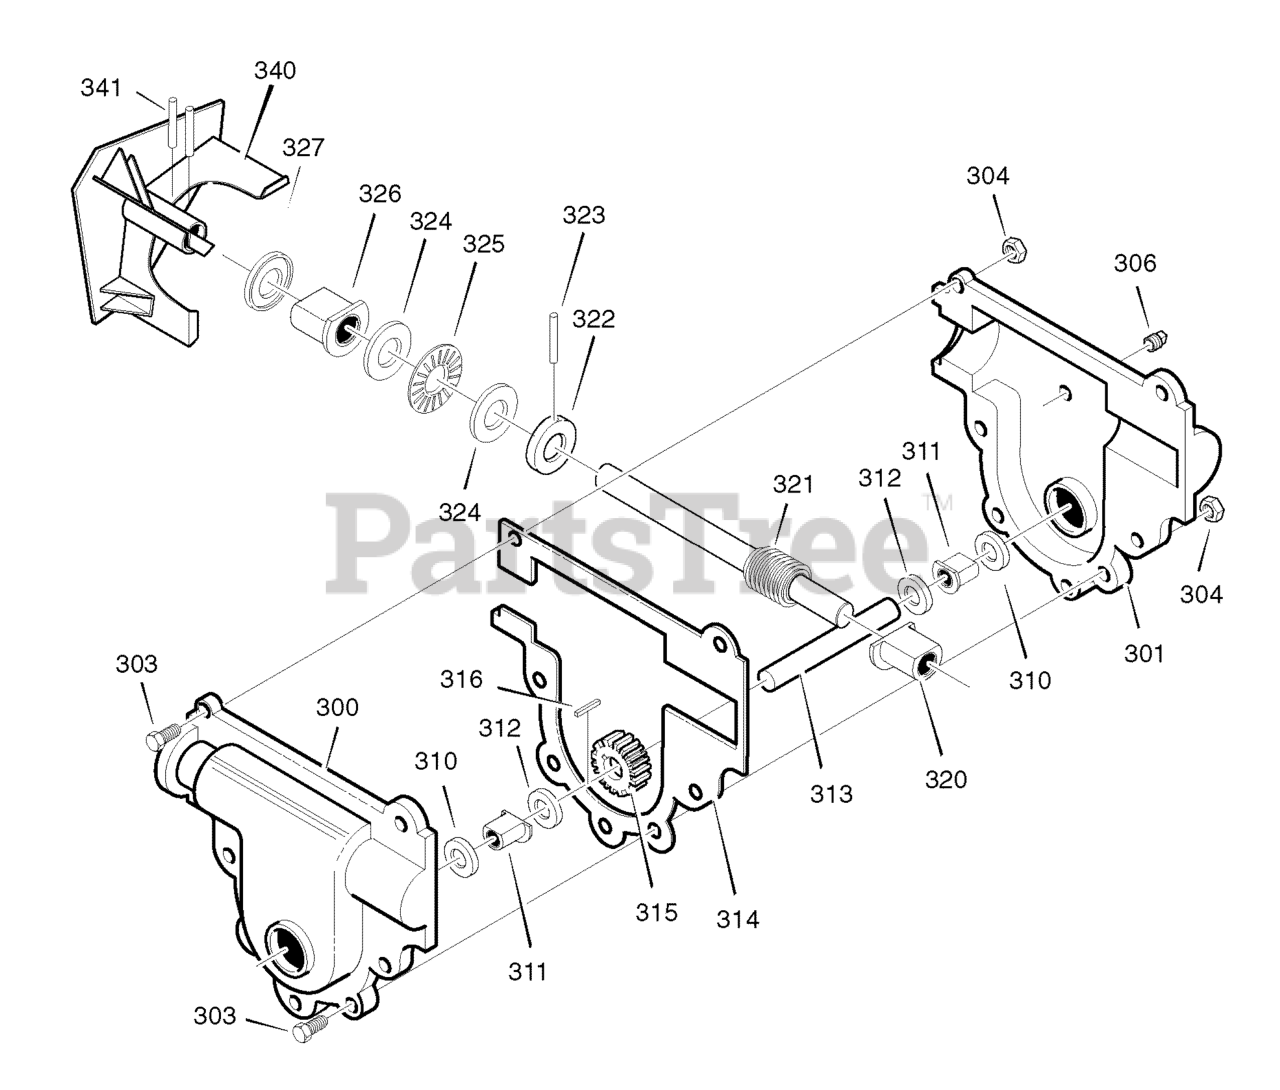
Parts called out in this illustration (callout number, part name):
300	CASE, GEAR, RH
301	CASE, GEAR, LH
306	SCREW
310	SEAL, OIL
311	BEARING, FLANGE
312	WASHER, FLAT
313	SHAFT, OUTPUT
315	GEAR, WORM
316	KEY, WOODRUFF
320	BEARING, FLANGE
321	SHAFT, INPUT
322	COLLAR, THRUST
323	PIN, SPRING
324	WASHER, FLAT
325	BEARING, ROLL
326	BEARING, FLANGE
327	SEAL, OIL
340	IMPELLER ASSEMBLY
341	PIN, SPRING
